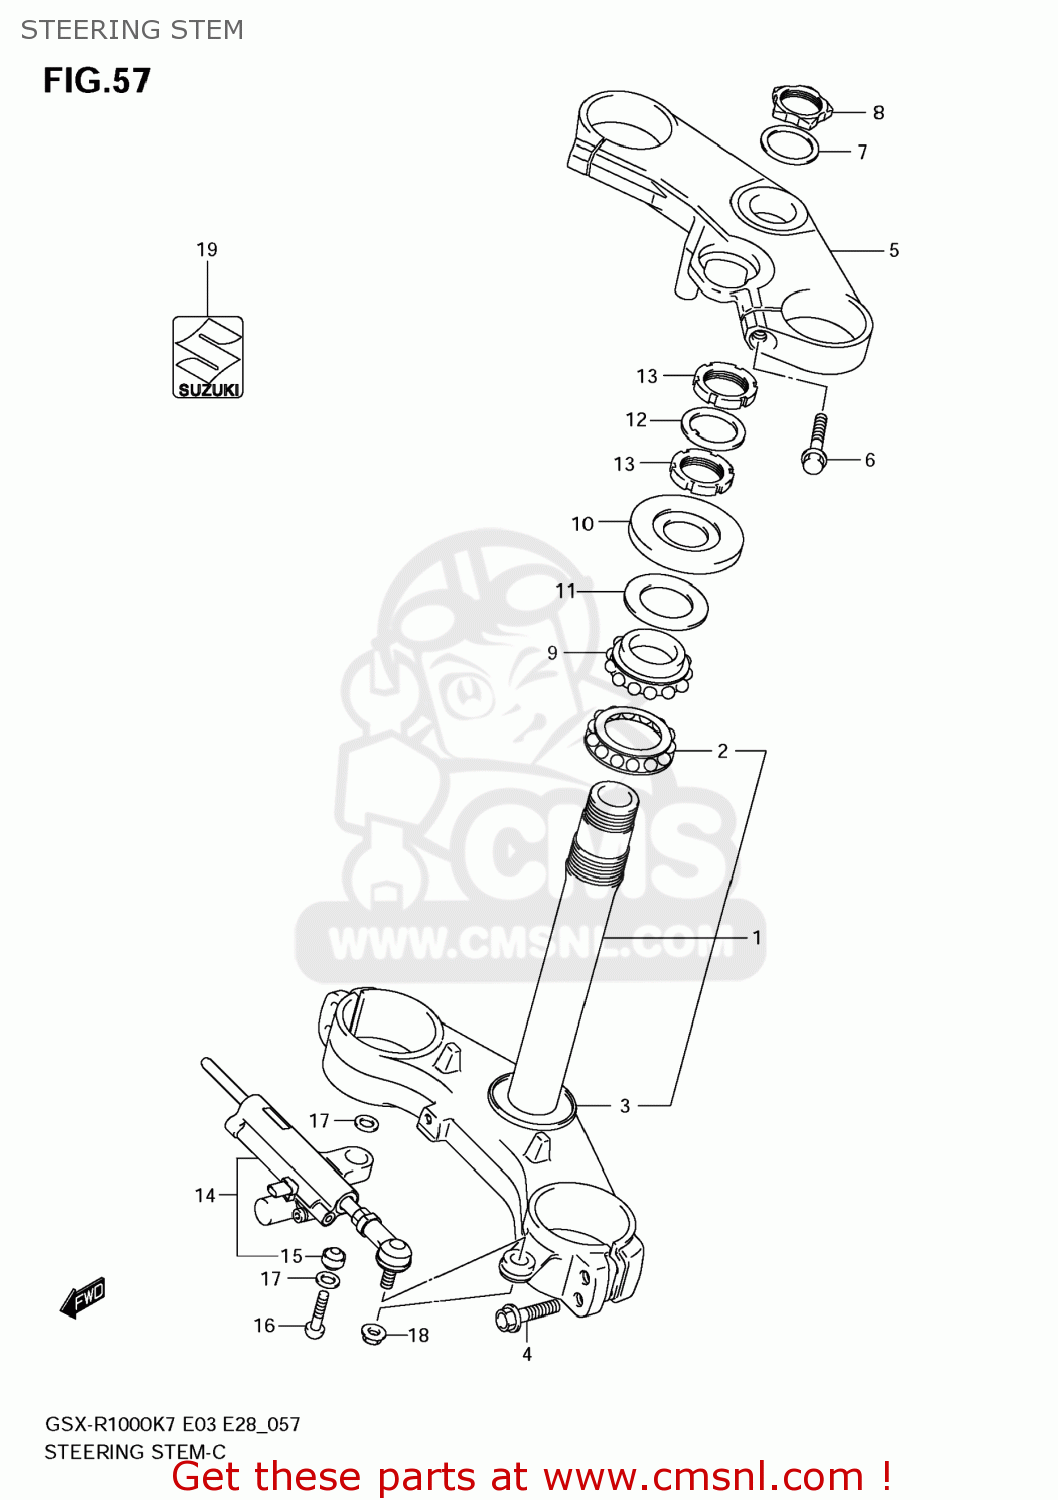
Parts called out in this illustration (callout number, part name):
1	BRACKET,UNDER
2	BEARING(30X55X17)
3	SEAL,STEERING LWR
4	BOLT,LWR
5	BRACKET,UPR
6	BOLT
7	WASHER
8	NUT
9	BEARING(30X55X17)
10	COVER,STEERING UPR
11	SEAL,STEERING LWR
12	WASHER,STEERING STEM
13	NUT,STEERING STEM
14	DAMPER ASSY,STEERING
15	BEARING(8X17.5X11)
16	BOLT(8X35)
17	SEAL,PILLOW BALL,DUST
18	NUT
19	EMBLEM,S
